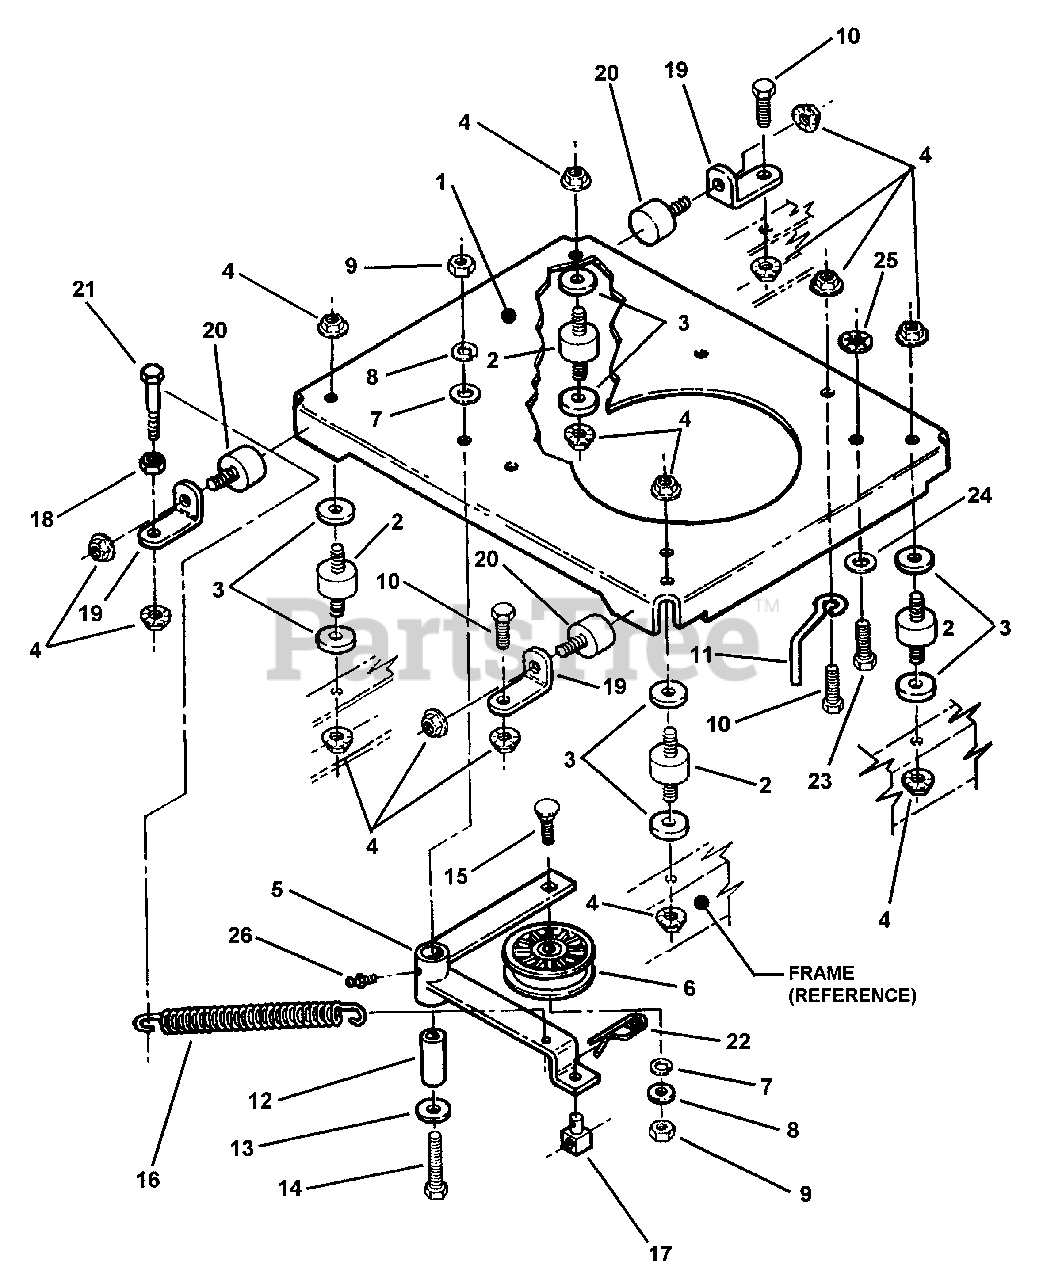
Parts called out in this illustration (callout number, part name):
1	PLATE, Engine
2	ISOLATOR
3	WASHER, 7/16" I.D. x 1-3/8" O.D. x 1/4" Thick Flat
4	NUT, 3/8-16 Hex Flange Lock
5	WELDMENT, Idler/Brake
6	PULLEY, 3.47 O.D. Flat Idler
7	WASHER, 3/8" Flat
8	WASHER, .38 I.D. x .68 O.D. x .09 Thick Flat
9	NUT, 3/8-16 Hex, Grade 5 or B
10	BOLT, 3/8-16 x 1" Hex Flange Lock, Grade 5
11	GUIDE, Engine Belt
12	SPACER, Pivot Collar
13	WASHER, Special
14	SCREW, 3/8-16 x 2-1/2" Hex Head Cap, Grade 5
15	BOLT, 3/8-16 x 1-3/4" Short Neck Carriage, Grade 5
16	SPRING, Primary Idler
17	SWIVEL, 3/8 Brake Link
18	NUT, 3/8-16 Hex Jam
19	BRACE, Snubber Mount
20	MOUNT, Snubber
21	SCREW, 3/8-16 x 1-1/2" Hex Head Cap, Grade 5
22	COTTER-PIN, 1/16" x 1.42" Self-Locking
23	SCREW, 5/16-24 x 1-3/4" Hex Head Cap, Grade 5
24	WASHER, .344 I.D. x 11/16 O.D. x 1/16" Thick Flat
25	RETAINER, 5/16" Bolt (Black)
26	FITTING, 3/16 Lube
